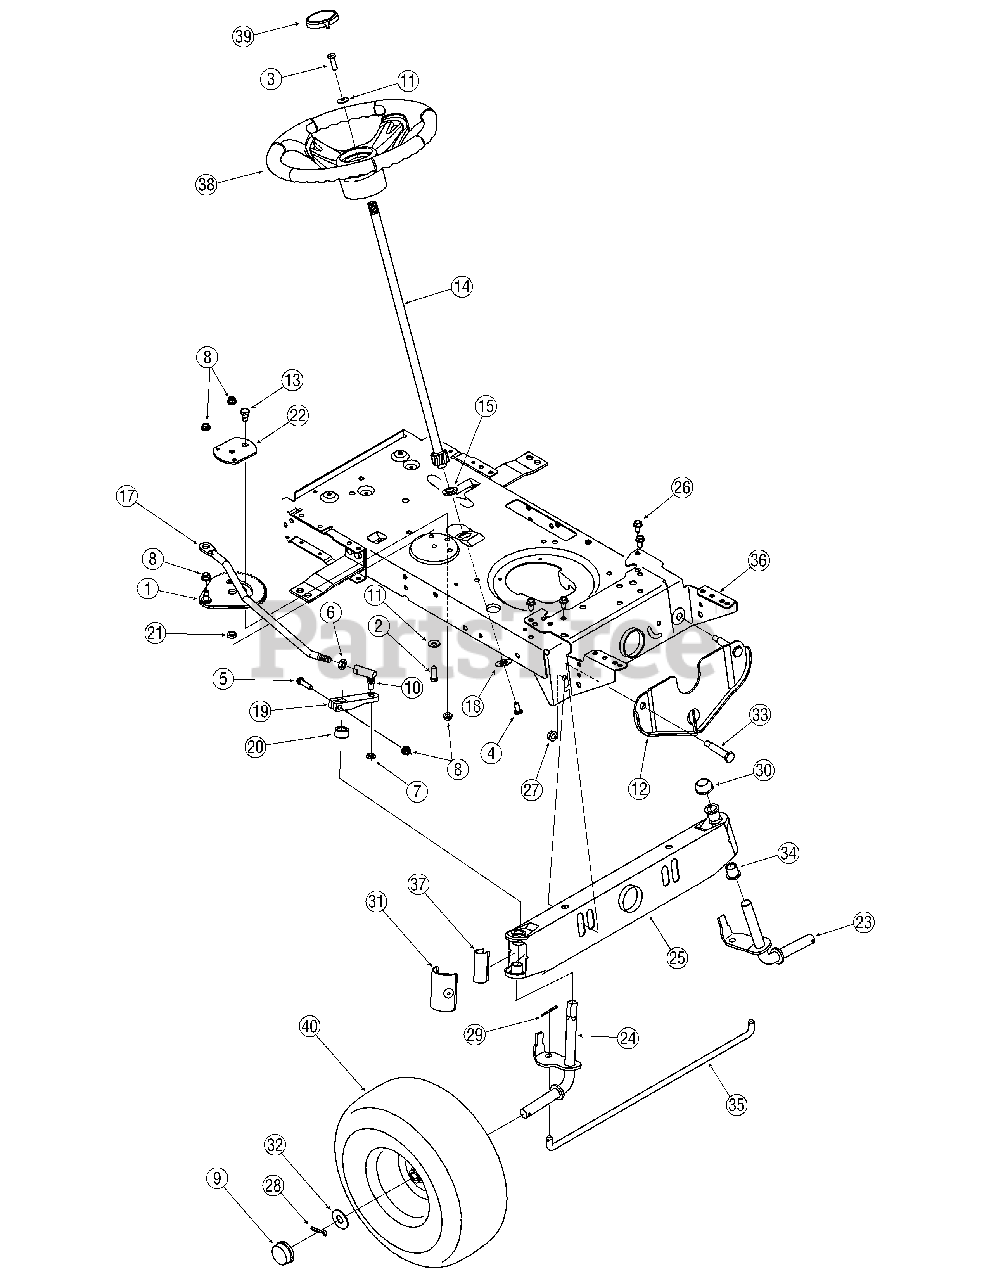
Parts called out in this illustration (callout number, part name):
1	Gear Assembly, Steering
2	Screw, 5/16-18, 1.00, Gr5
3	Screw, 5/16-18, 1.00, Gr5, Lock
4	Screw, Mach, 5/16-18, 0.750
5	Screw, 5/16-18, 1.75, Gr5
6	Nut, Jam, 7/16-20, Gr2
7	Nut, Jam Lock, 3/8-24, Gr2
8	Nut, Flange Lock, 5/16-18, Grf, Nylon
9	Hub Cap
10	Ball Joint, 7/16-20, Lock
11	Washer, Bell, .340 x .872 x .060
13	Screw, Shoulder, .435 x .3485, 5/16-18
14	Steering Shaft, 5/8 Spline x 21.86
15	Bearing, Flange, Hex 5/8
16	Plastic Bushing .380 ID
17	Drag Link, Steering
18	Cap, 1.25 x .16
20	Spacer, .710 ID x .125 OD x .56
21	Spacer, .322 ID x .625 OD x .21
22	Stabilizer Plate, Gear Segment
26	Screw, 5/16-12, 0.750
27	Nut, Flange Lock, 3/8-16, GrF, Nylon
28	Pin, Cotter, 5/32, 1.25
29	Pin, Cotter, 1/8 x 1.25
30	Push Cap, 3/4
31	End Cap, Pivot Bar (w/ Fitting)
32	Washer, Flat, .78 x 1.59 x .060
33	Screw, Shoulder, .500 x 2.380, 3/8-16
34	Bearing, Flange, .760 x .941 x 1.0
37	Axle End Cap, Standard
38	Steering Wheel, Standard Grip
38	Steering Wheel, Soft Grip
39	Cap, Steering Wheel (no logo)
39	Cap, Steering Wheel (sprig logo)
39	Cap, Steering Wheel (tine logo)
